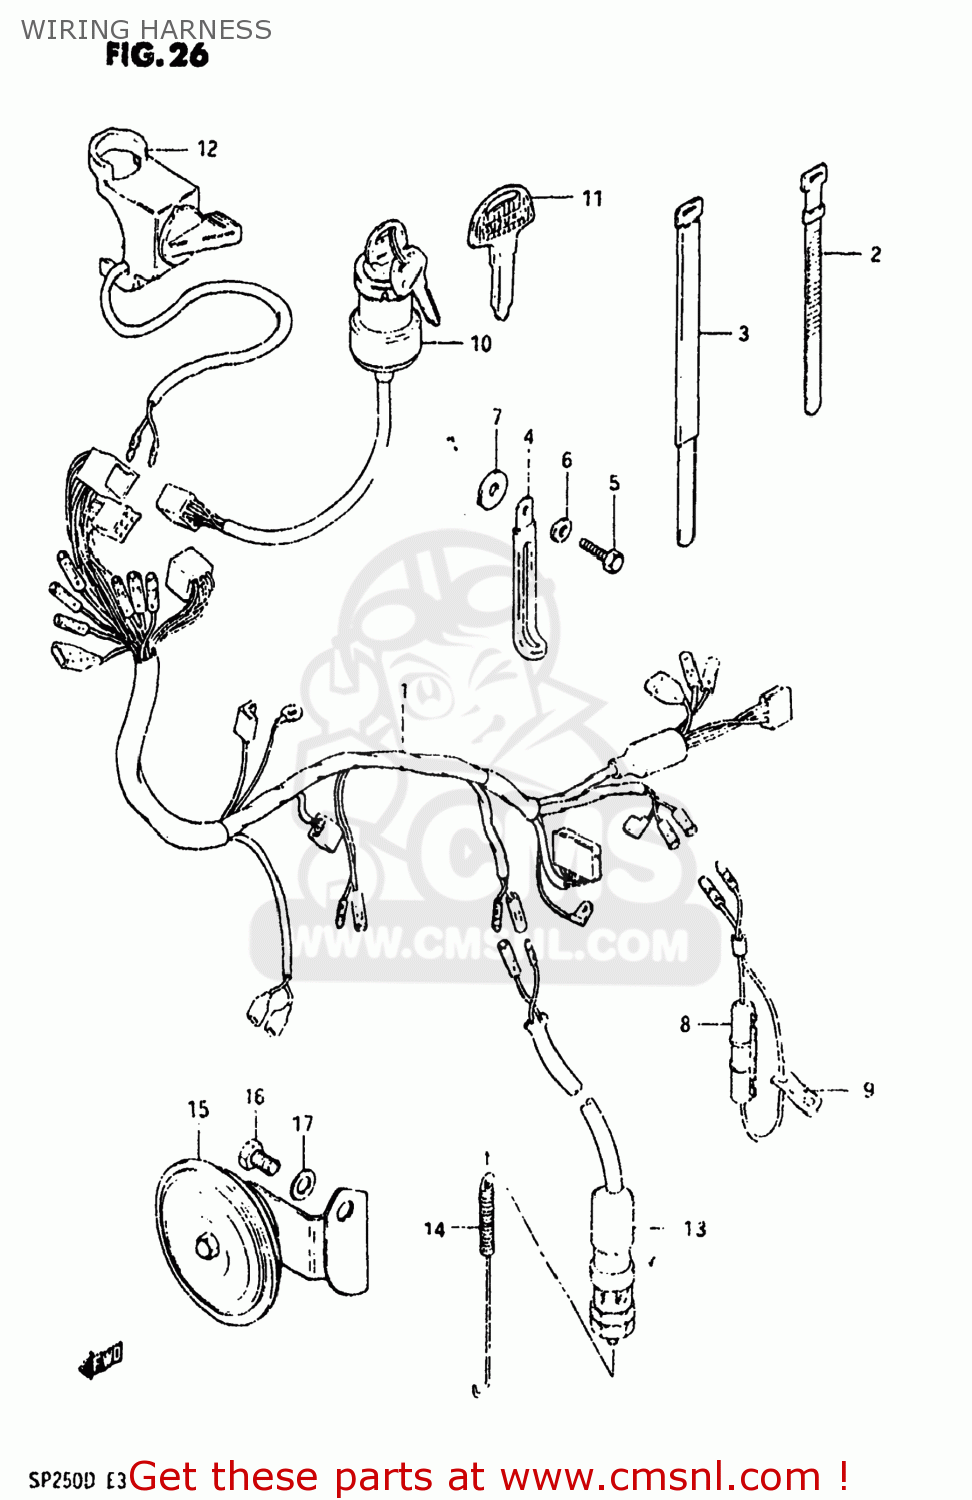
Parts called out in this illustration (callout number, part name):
1	HARNESS,WIRING
2	CLAMP(L:120)
3	CLAMP
4	CLAMP
5	BOLT, UPPER
6	WASHER
7	WASHER
8	BOX ASSEMBLY,FUSE
9	FUSE(15A)
10	SWITCH ASSEMBLY,IGNITION
11	KEY,BLANK
12	SWITCH ASSY,ENGINE STOP
13	SWITCH ASSEMBLY,STOP LAMP
14	SPRING
15	HORN ASSEMBLY
16	BOLT
17	WASHER
